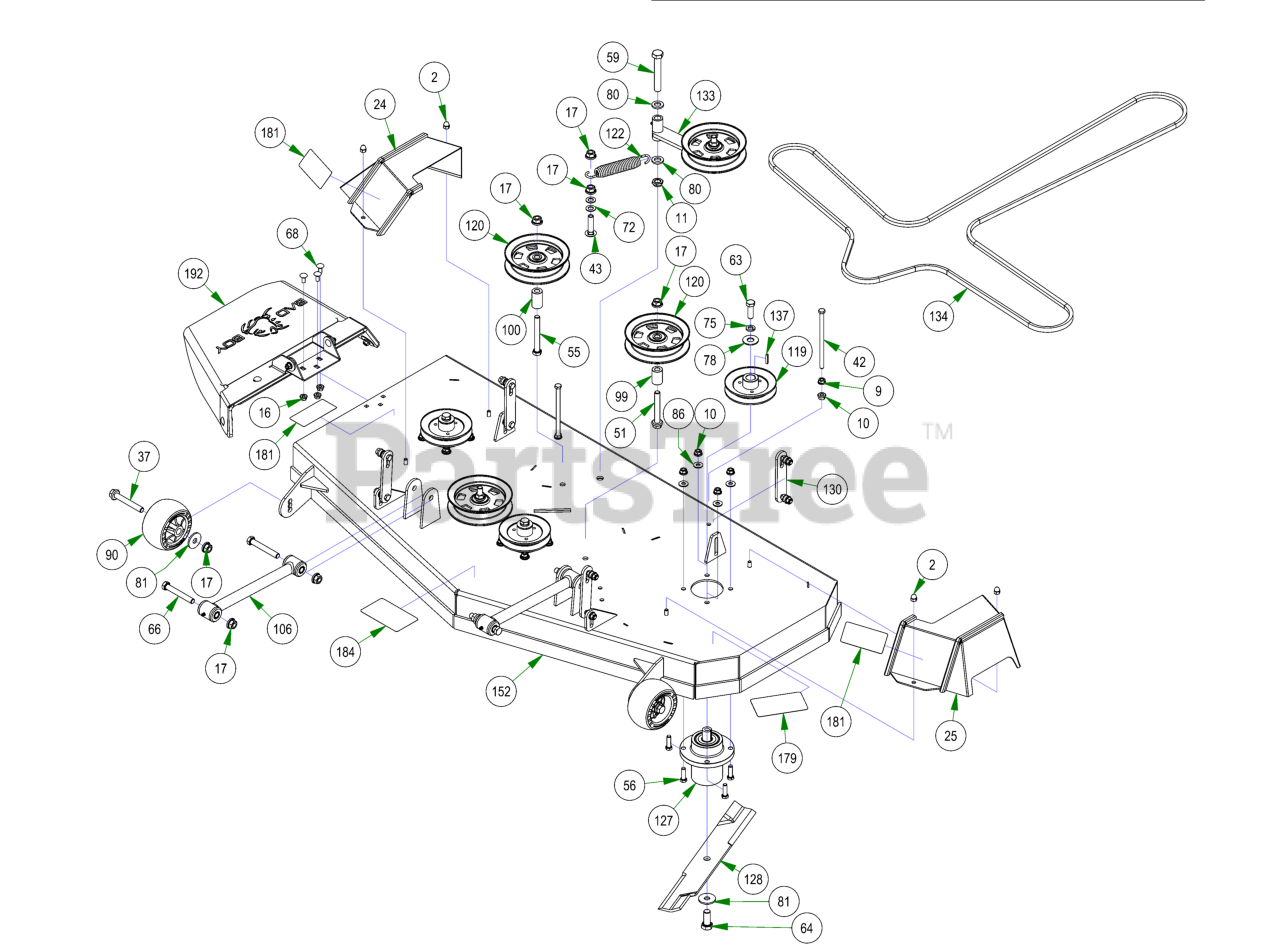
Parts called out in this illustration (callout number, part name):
2	5/16-18 ACORN NUT HIGH-CROWN ZC
9	3/8-16 HEX SERRATED FLANGE NUT HARD/ZINC
10	3/8-16 NYLON INSERT FLANGE LOCKNUT (GR.F) ZINC
11	5/8-11 NYLON INSERT JAM LOCKNUT ZINC
16	5/16-18 NYLON INSERT FLANGE LOCKNUT ZINC
17	1/2-13 NYLON INSERT FLANGE LOCKNUT ZINC
24	2021 Maverick 54”/60” RH Pulley Cover
25	2021 Maverick 54”/60” LH Pulley Cover
37	1/2-13 X 90MM HEX FLANGE BOLT W/SHOULDER (GR.8) ZINC
42	3/8-16 X 6.5 HEX CAP SCREW (GR.5) ZINC
43	1/2-13 X 2 CARRIAGE BOLT ZINC
51	1/2-13 X 3-1/2 HEX FLANGE BOLT (GR.8) ZINC
55	1/2-13 X 4 HEX CAP SCREW (GR.8) ZINC YELLOW
56	3/8-16 X 1-1/4 HEX CAP SCREW (GR.5) ZINC
59	5/8-11 X 4 HEX CAP SCREW (GR.8) ZINC YELLOW
63	1/2-20 X 1-1/2 HEX CAP SCREW (GR.5) ZINC
64	5/8-18 X 1-1/2 HEX CAP SCREW (GR.8) ZINC YELLOW
66	1/2-13 X 3-1/2 HEX CAP SCREW (GR.5) ZINC
68	5/16-18 x 3/4 Carriage Bolt
72	.517 SQ WDTH ID X .937 OD X .060 THICK F/W PHOS/OIL
75	1/2 SPLIT LOCKWASHER (GR.8) ZINC/YELLOW
78	5/8 USS FLAT WASHER (1-3/4" OD) GR.8 ZINC YELLOW
80	.635 ID X 1.120 OD X .140 THICK FLAT WASHER NYLON
81	1/2 BELLEVILLE WASHER (1-5/8 OD X .140 THK) ZINC
86	5/16 USS FLAT WASHER (7/8 OD) ZINC
90	Deck Wheel
99	.502 ID X .750 OD X 1.500 Long Spacer
100	1 3/4" Pulley Spacer
106	Hybrid Turnbuckle/Deck Locator
119	54 MZ Spindle Pulley
120	5-3/4 Idler Pulley
122	Deck Idler Spring
127	Spindle Assembly-MZ
128	54" Fusion Blade for ZT/Mav/Outlaw/Revolt
130	Deck Hanger Assembly
133	2017 54"/48" Deck Idler Assembly
134	B155.75 Deck Belt
137	3/16 X 1 SQ MACHINERY KEY 1018 STL ZINC
152	2017 54" MZ Magnum Deck
179	2018 54" Deck Decal
181	Danger Decal-Spindle/Discharge
184	Deck Belt Route Decal
192	MZ Discharge Chute Assembly
